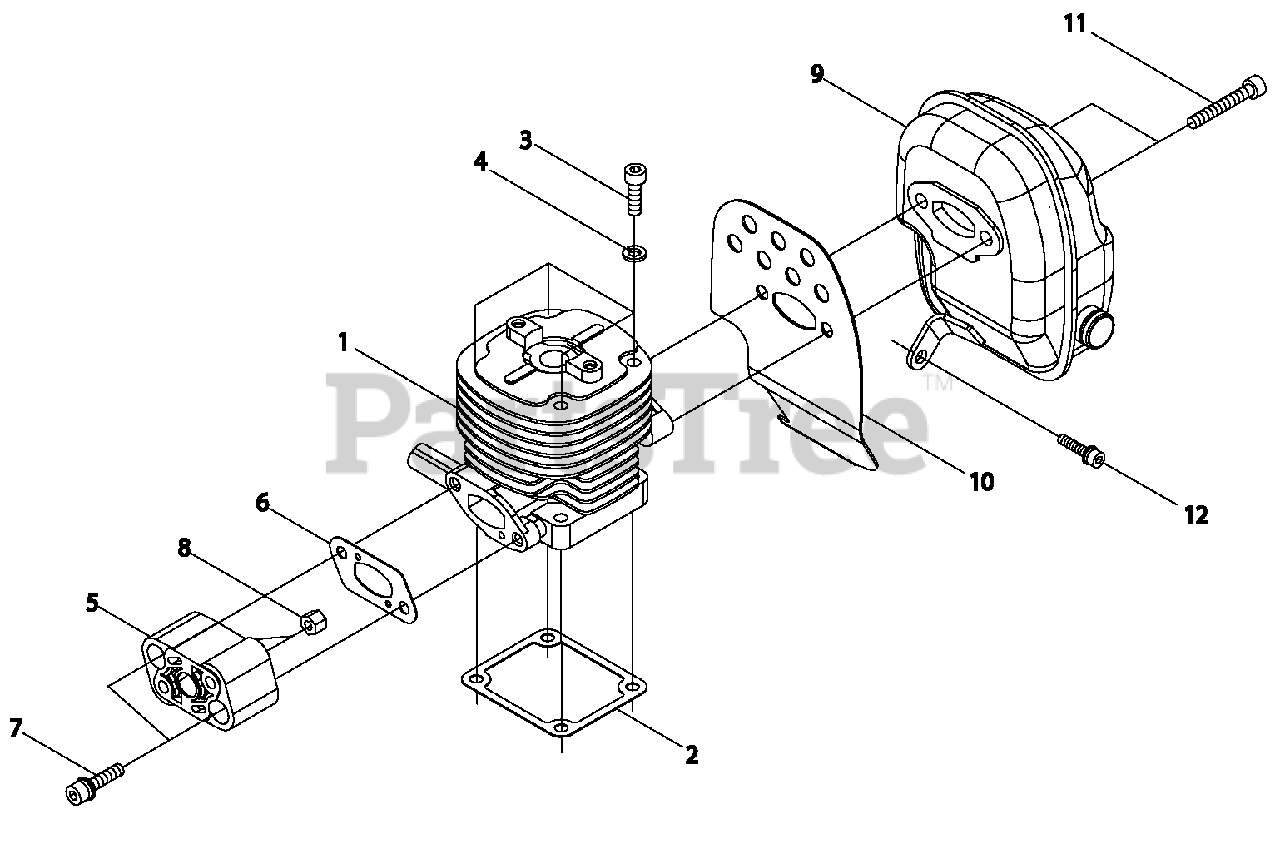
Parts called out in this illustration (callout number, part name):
1	CYLINDER
2	GASKET, CYLINDER
3	SCREW - 5X25
4	LOCKWASHER - 5
5	INSULATOR, INTAKE
6	GASKET, INTAKE
7	SCREW - 5X25
8	NUT - 5X6.3
9	MUFFLER
10	SHIELD, EXHAUST
11	SCREW - 6X25
12	SCREW - 5X12
